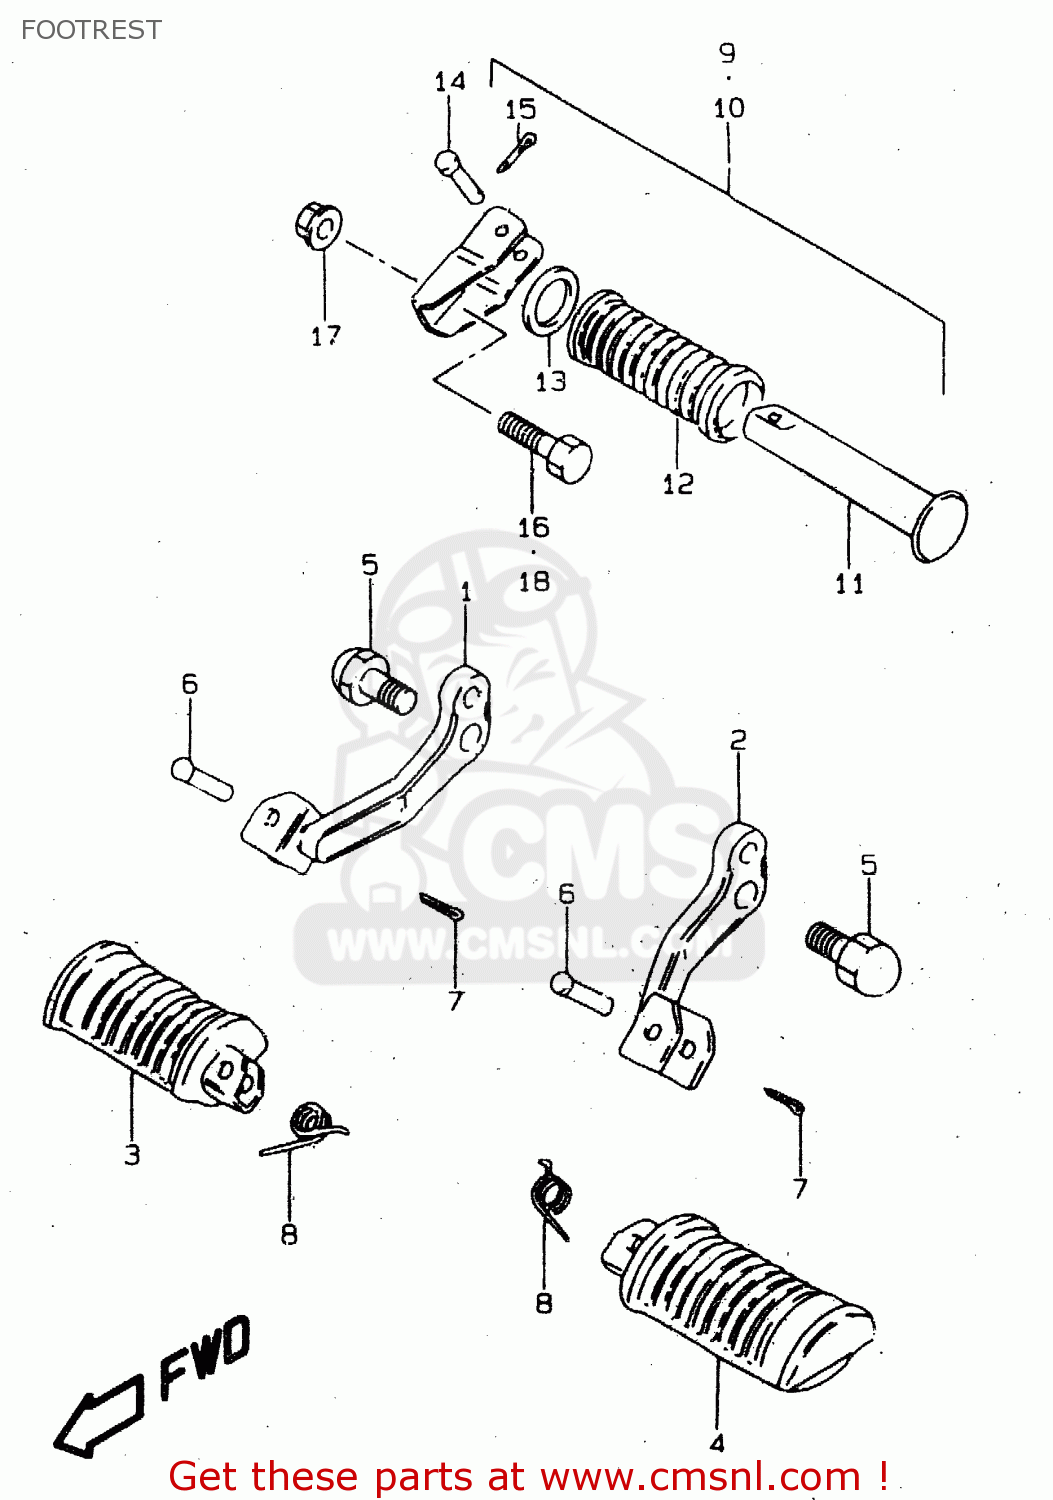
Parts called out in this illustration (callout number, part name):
1	HOLDER,FR FOOTREST,R
2	HOLDER,FR FOOTREST,L
3	RUBBER,PILLION FOOTREST,R
4	RUBBER,PILLION FOOTREST,L
5	BOLT
6	PIN
7	PIN 20X20
8	SPRING
9	FOOTREST ASSY,PILLION,R
10	FOOTREST ASSY,PILLION,L
11	BAR,FOOTREST RUBBER
12	RUBBER,PILLION FOOTREST
13	WASHER
14	PIN
15	PIN
16	BOLT
17	NUT
18	BOLT
